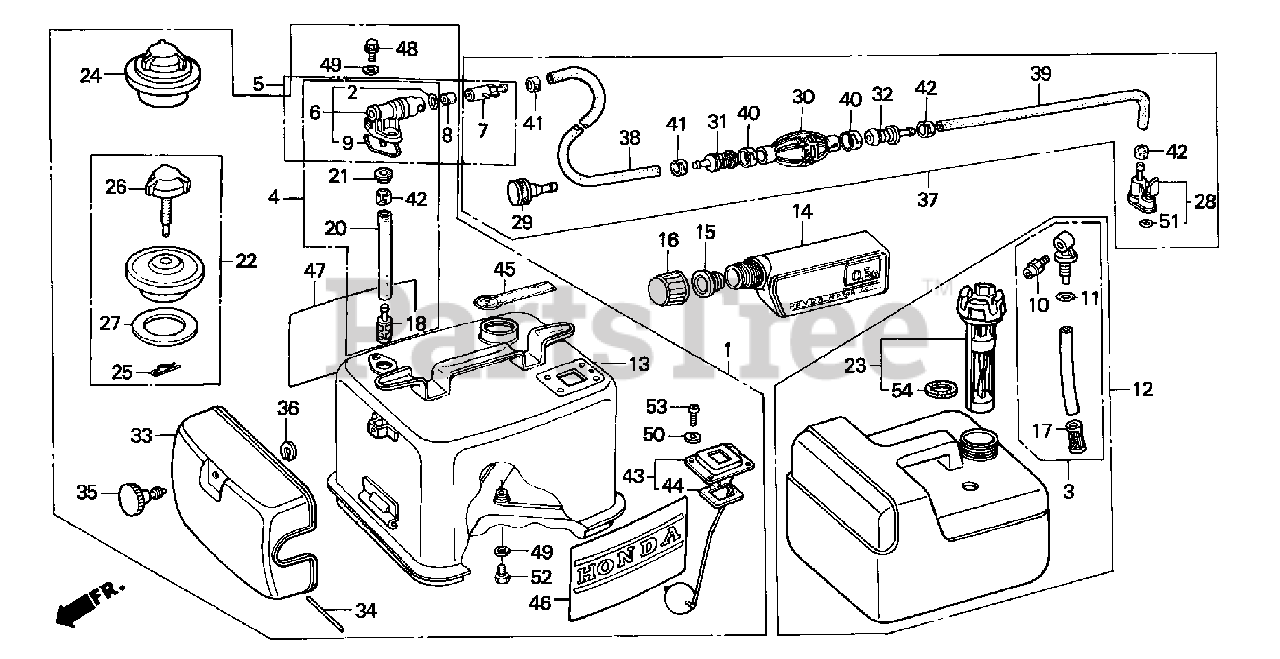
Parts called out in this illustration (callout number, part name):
3	JOINT ASSY., FUEL
10	FITTING, QUICK DISCONNECT
11	O-RING
12	TANK ASSY., FUEL
17	FILTER, FUEL
23	CAP, FUEL FILLER
28	CONNECTOR, FUEL *NH1* (BLACK)
29	CONNECTOR, FUEL
30	PRIMER BULB
31	VALVE, IN.
32	VALVE, OUTLET
37	TUBE, FUEL *NH1* (BLACK)
38	TUBE, FUEL (7.5X2000)
39	TUBE, FUEL SHORT
40	BAND, TUBE CLIP (20MM)
41	BAND, TUBE CLIP (12.5MM)
42	BAND, TUBE CLIP (11MM)
51	O-RING (5.5X3)
54	GASKET, FUEL CAP
